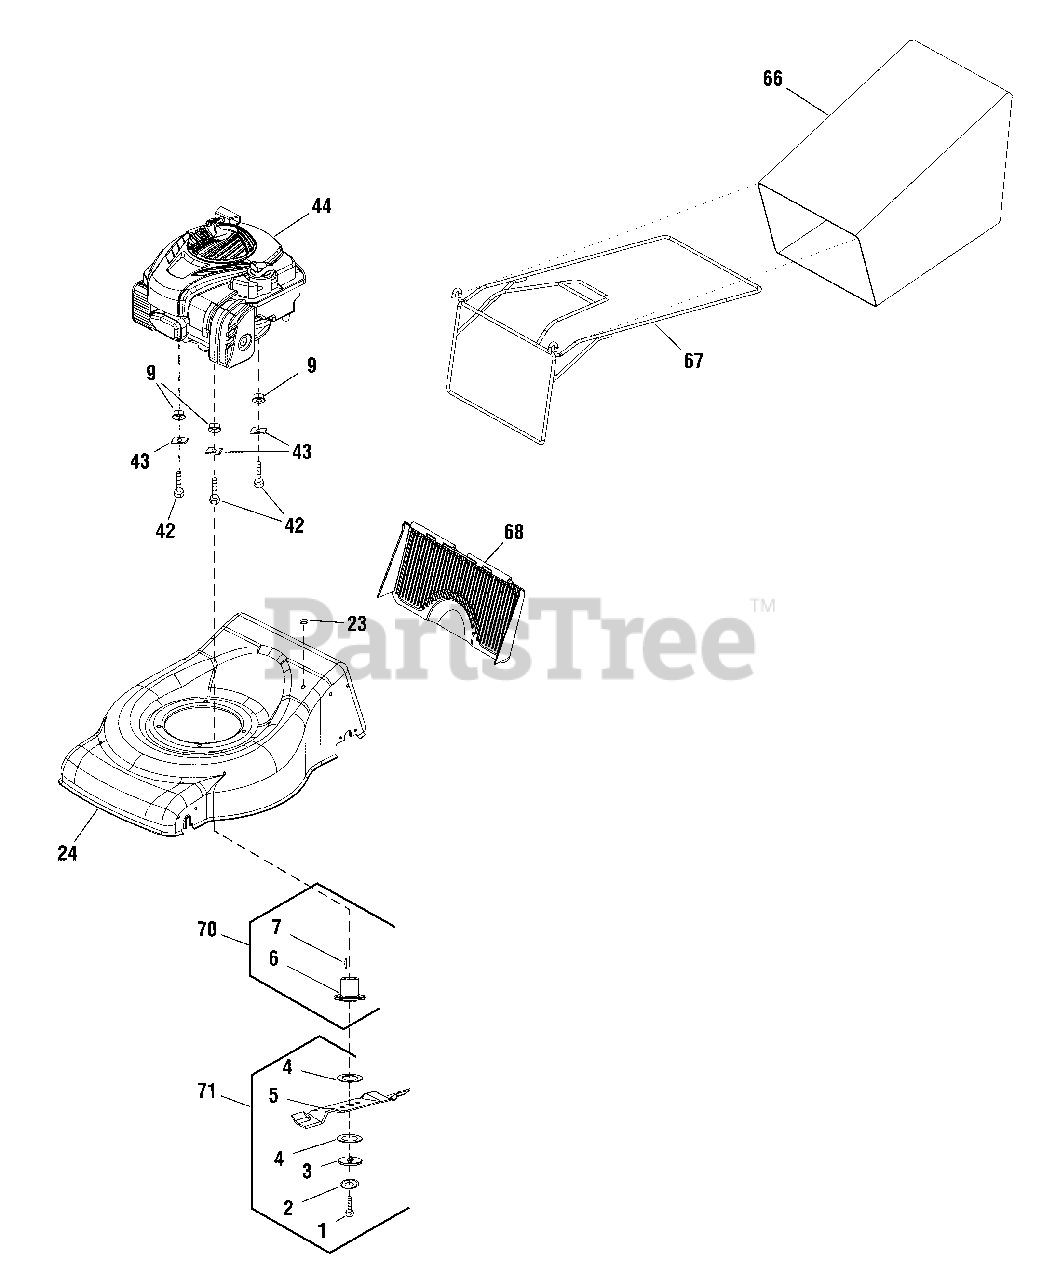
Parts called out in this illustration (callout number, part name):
1	BOLT, Blade
3	PLATE, Blade Support
4	PLATE, Blade
6	SUPPORT, Blade
9	* NUT, Hex Lock
23	GROMMET
42	* BOLT, Hex
43	WASHER, Square
44	** ENGINE, Briggs & Stratton 450E Series
66	BAG, Grass
68	COVER, Rear
70	KIT, Blade Adapter
71	KIT, Blade
